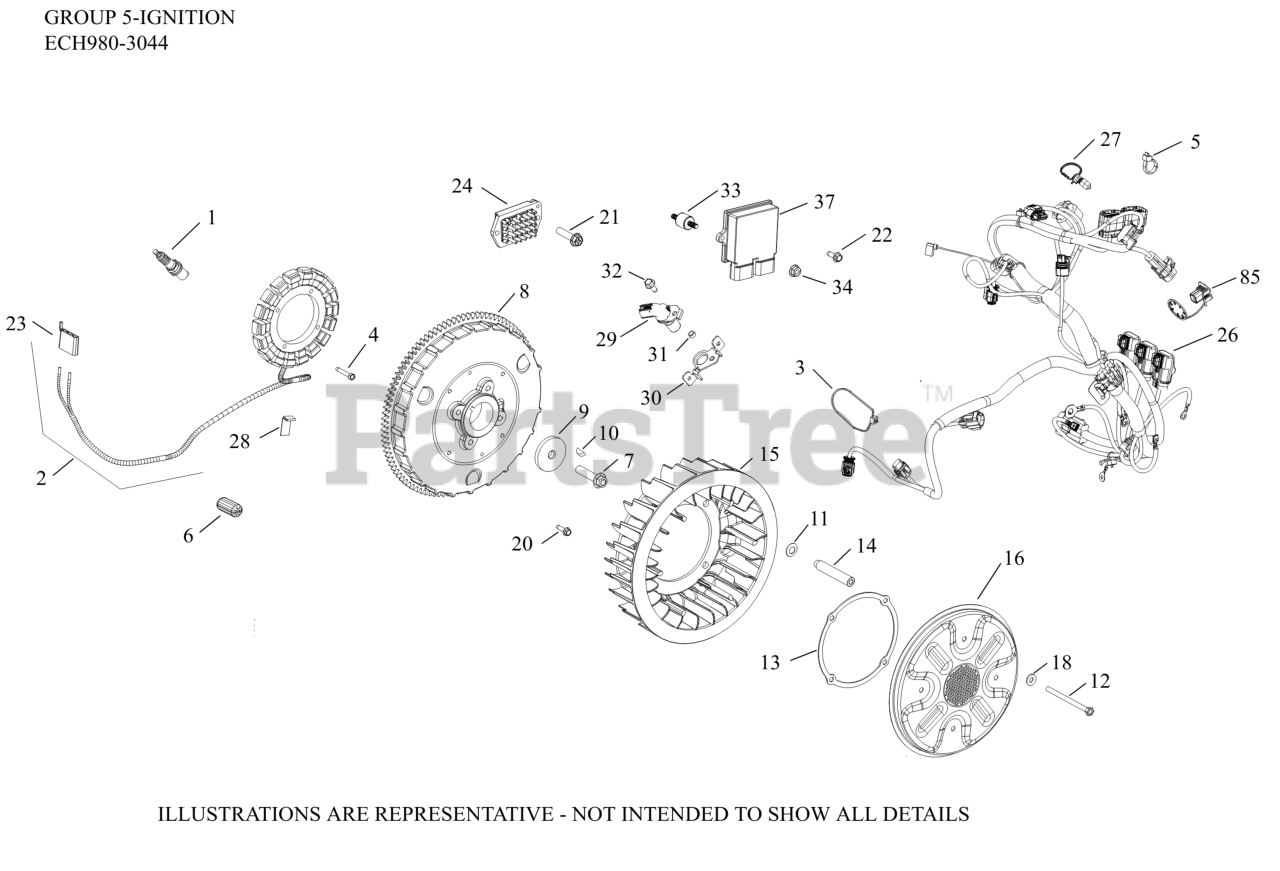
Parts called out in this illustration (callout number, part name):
1	PLUG, SPARK
2	KIT, 25 AMP STATOR ASSY.
3	TIE, CABLE
4	SCREW, THREAD FORMING
5	TIE, WIRE
6	SLEEVE, EMI SUPPRESSION
7	SCREW, FLG M10X1.5X45-USE 25 086 361-S
8	FLYWHEEL ASSEMBLY
9	WASHER, FLAT 13/32"
10	KEY, 3/16" X 5/8"
11	WASHER, SPRING 10 MM
12	SCREW, HEX HEAD
13	RING, SUPPORT
14	SPACER, GRASS SCREEN
15	FAN
16	SCREEN, GRASS
18	WASHER, FLAT 1/4" (O.D. 5/8")
20	SCREW, THREAD FORMING
21	SCREW, HEX FLANGE HI-LO
22	SCREW, THREAD FORMING
23	CONNECTOR
24	REGULATOR, RECT (20-30AMP, FW W/OVP)
26	HARNESS, WIRING ASSEMBLY - EFI
27	TIE, WIRE
28	CLIP, BLOWER HOUSING
29	SENSOR, SPEED
30	BRACKET, CRANK SENSOR
32	SCREW, THREAD FORMING
33	ISOLATOR, VIBRATION STUD
34	NUT, FLG M5X.8
37	MODULE, ECU ECH 980
85	CAP, CONNECTOR (4-WAY, BLACK)
